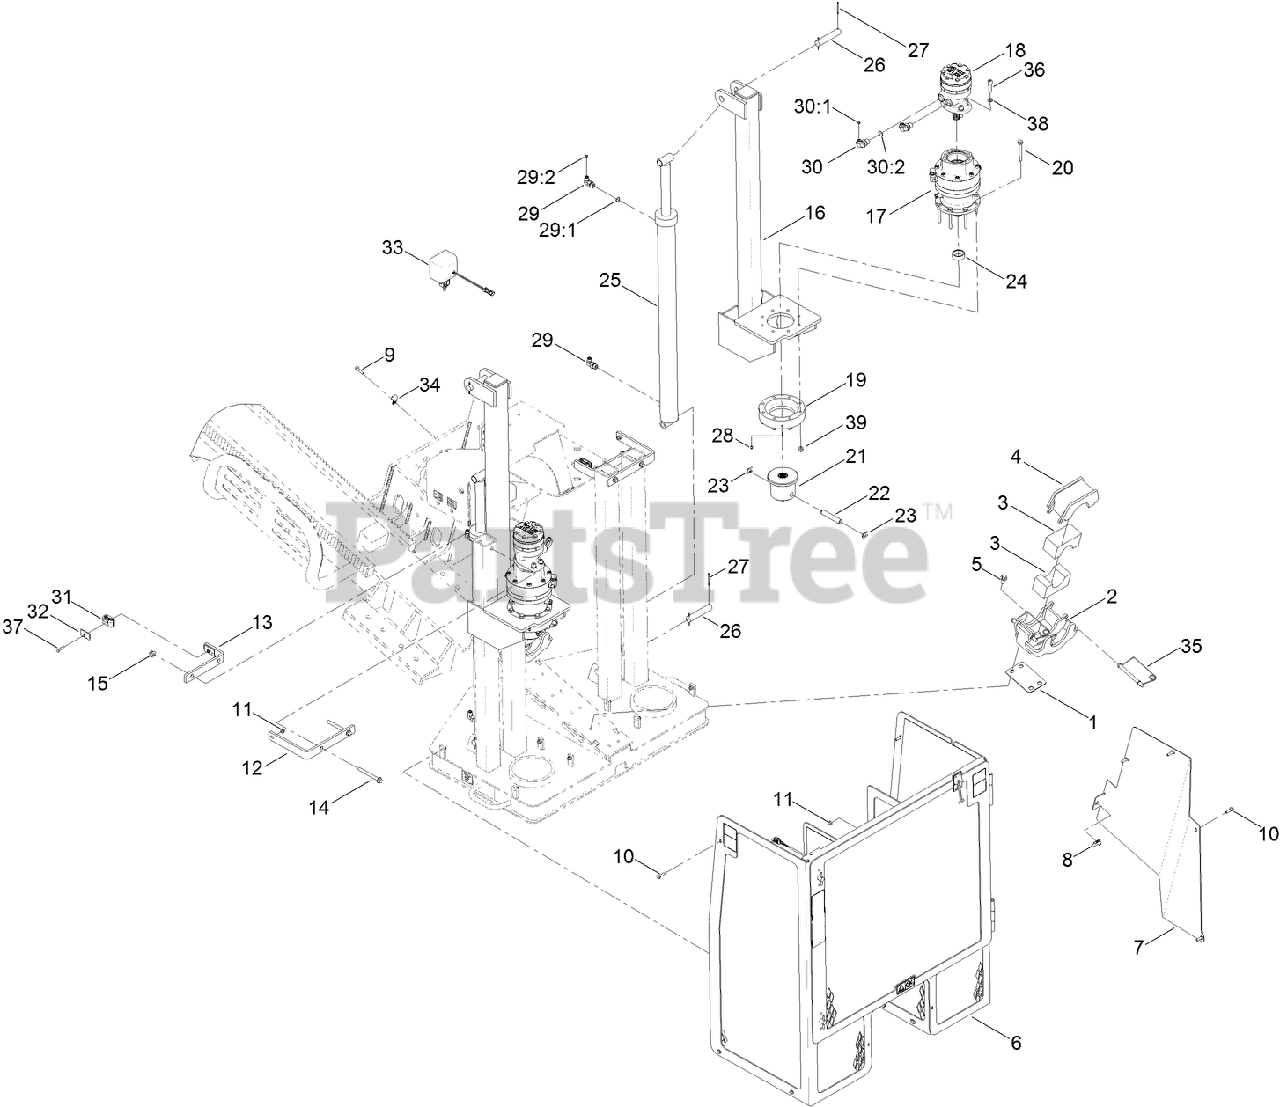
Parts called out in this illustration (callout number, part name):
1	PLATE-SHIM, BUSHING GUIDE
2	GUIDE-ROD, LOWER
3	BUSHING-GUIDE, ROD
4	GUIDE-ROD, UPPER
5	SCREW-HHF
6	STAKEDOWN CAGE ASM
7	PLATE-GUARD
9	SCREW-HHF
10	SCREW-HHF
11	NUT-LOCK, HHF
12	PLATE-MOUNT, STAKEDOWN
13	BRACKET ASM
14	SCREW-HHF
15	NUT-LOCK, HHF
16	STAKEDOWN
17	PLANETARY GEARBOX ASM
18	HYD MOTOR ASM
20	SCREW-HHF
21	COUPLER-AUGER DRIVE, STAKEDOWN
22	PIN-BAR, AUGER COUPLER
23	RING-RETAINING, E-TYPE
24	SPACER-TUBE
25	HYD CYLINDER ASM
26	PIN-BAR
27	PIN-COTTER
28	FITTING-GREASE
29	FITTING-HYD, 90 DEG
29:1	O-RING
29:2	O-RING
30	FITTING-ELBOW 90
30:1	O-RING
30:2	O-RING
31	CLAMP-HALF (SET OF 2)
32	PLATE-COVER, TWIN
33	LIGHT-WORK
34	R-CLAMP
35	PIN-LYNCH
36	SCREW-HSH
37	SCREW-HH
38	WASHER-LOCK
39	NUT-LOCK, NI
